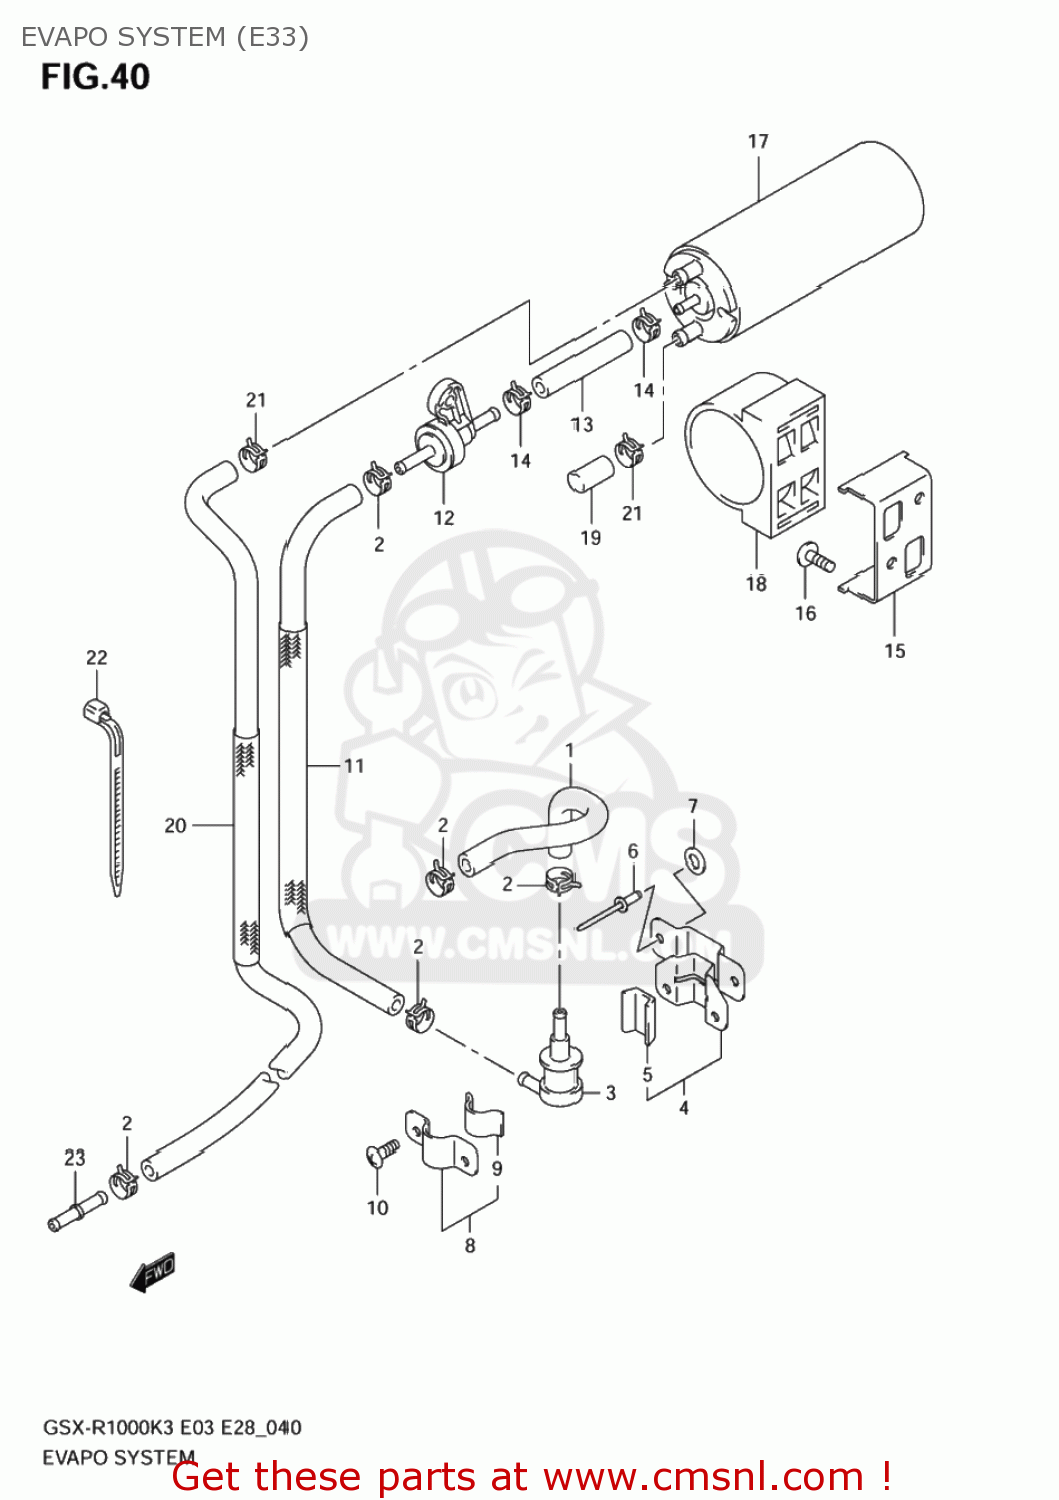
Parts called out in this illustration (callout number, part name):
1	HOSE,TANK & BREATHER VALVE
2	CLIP
3	VALVE,FUEL TANK BREATHER
4	PLATE,BREATHER VALVE
5	CUSHION
6	RIVET
7	WASHER
8	PLATE,FUEL TANK BREATHER NO.2
9	CUSHION
10	SCREW
11	HOSE,BRTHR VALVE & 2 WAY VALVE
12	VALVE,2 WAY & BREATHER VALVE
13	HOSE(5.4X11.4X600)
14	CLIP
15	BRACKET,CANISTER
16	SCREW(6X16)
17	CANISTER ASSY,CHARCOAL
18	CUSHION,CANISTER
19	CAP,OD:11.5
20	HOSE,CSTR PURGE
21	CLIP
22	CLAMP(L:120)
23	UNION
